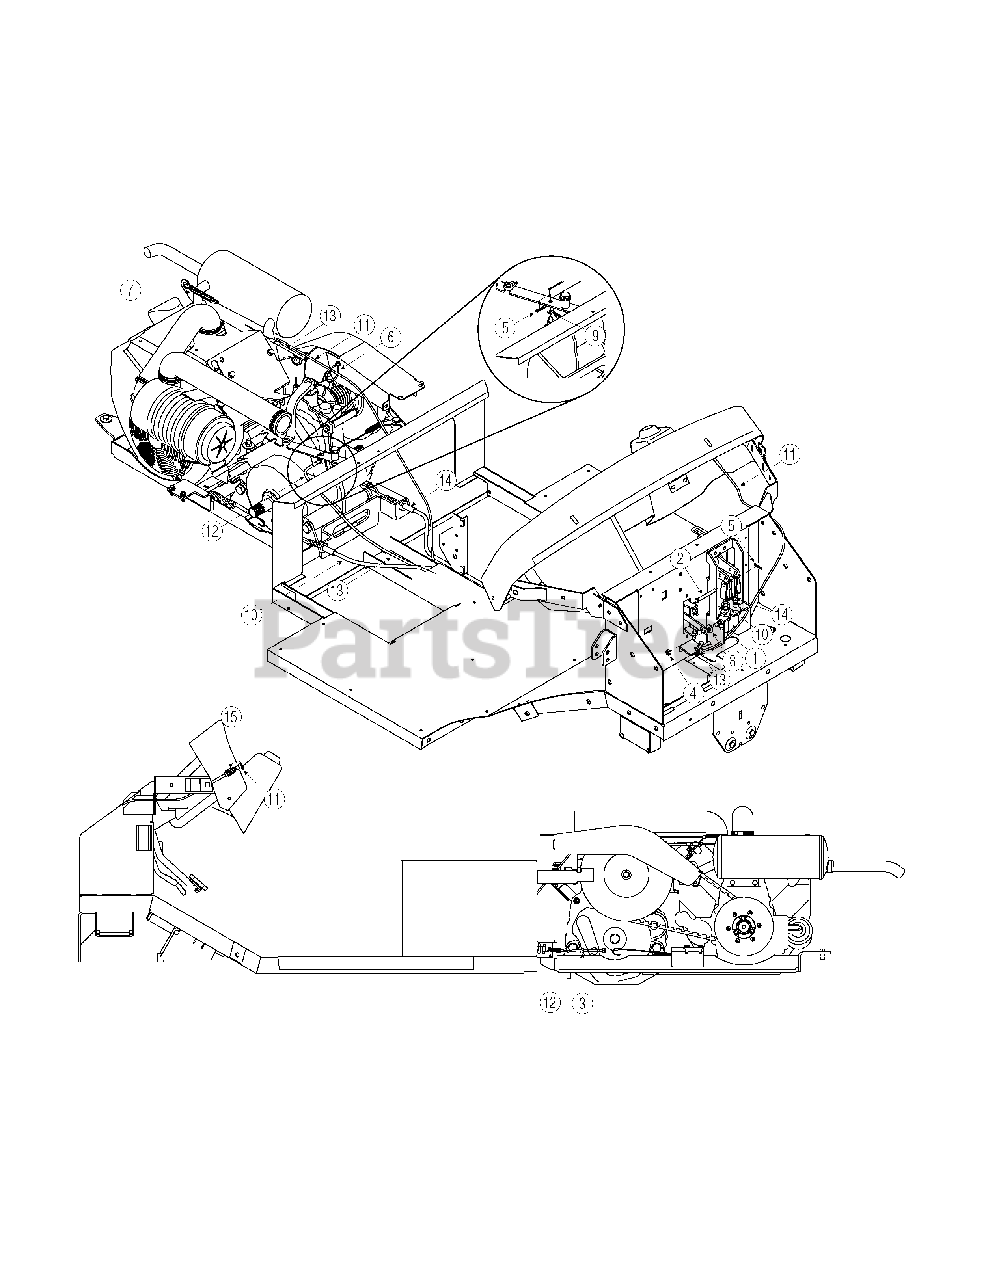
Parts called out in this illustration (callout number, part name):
1	Screw, Shoulder, .375 x .375
2	Pin, Clevis, 5/16 x 2.5
3	Nut, Jam, 5/16-24, Gr5
4	Nut, Hex Lock, 5/16-18
5	Pin, Cotter, .072 x 1.13
6	Cable Tie, Tree Mount
7	Extension Spring
8	Washer, .349 x .879 x .063
9	Washer, Spring, .317 x .879 x .063
10	Cable, Control, Brake
11	Cable, Control, Choke
12	Cable, Control, Clutch Brake
13	Cable, Control, Throttle
14	Cable, Control, Brake
15	Nut, Jam Lock 3/16-16, Gr5
